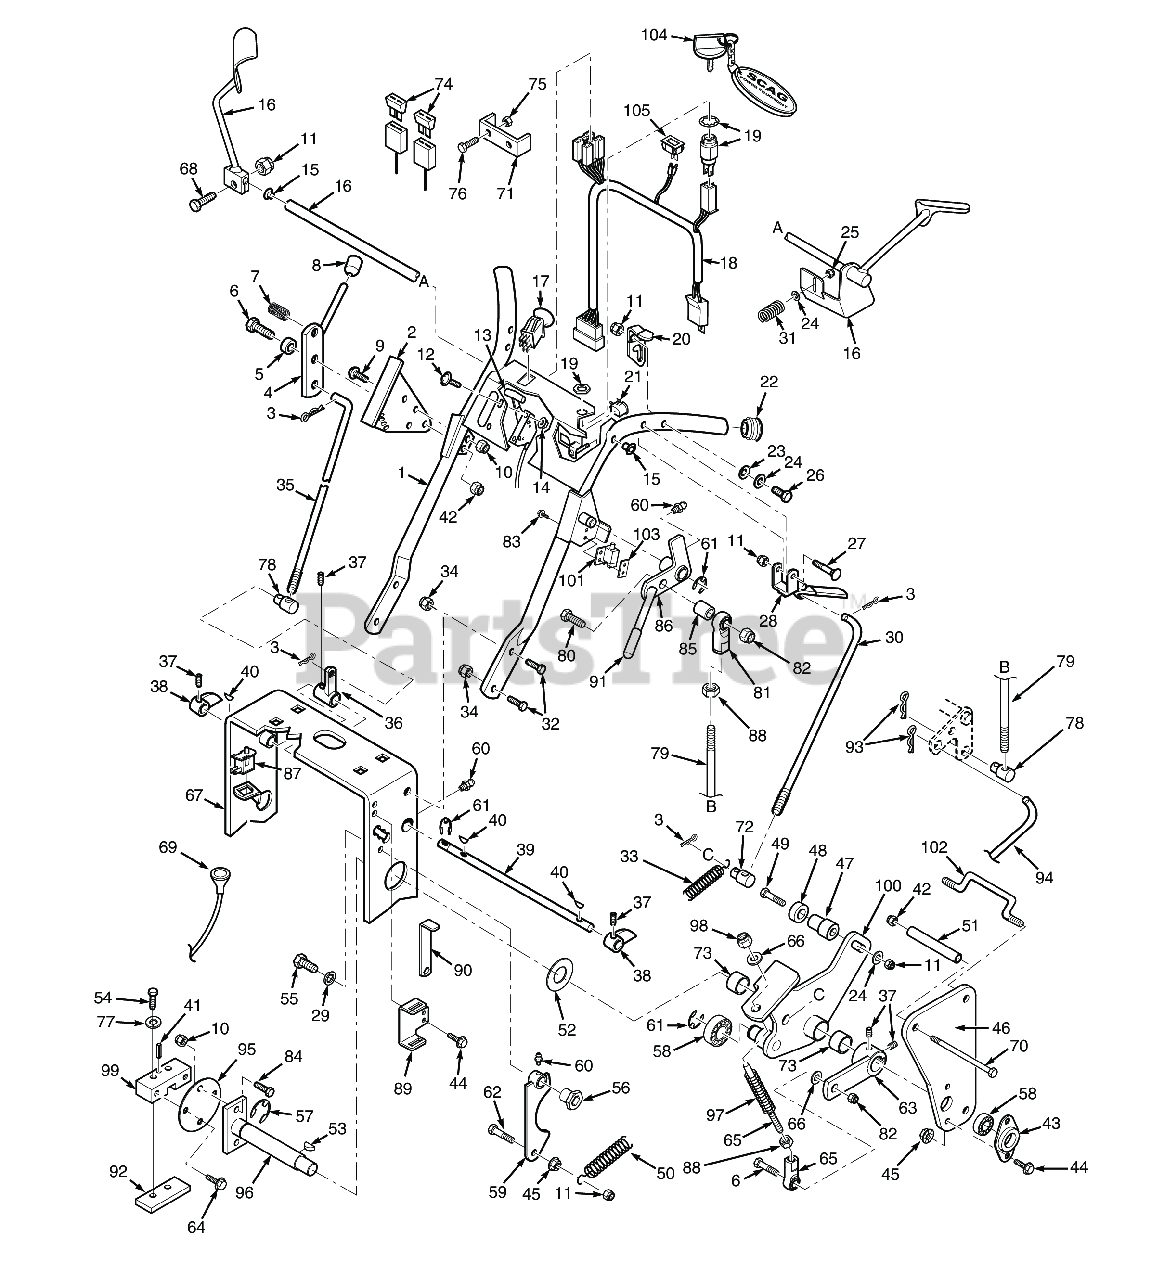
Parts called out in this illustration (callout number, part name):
1	Upper Handle Wlmt. W/Decals
2	QUADRANT, SPEED CONTROL
3	HAIR PIN, .08 DIAMETER X 1-3/16"
4	LEVER, SPEED ADJUSTMENT
5	BUSHING, SPEED ADJUSTMENT LEVER
6	Bolt, Hex Head, 3/8-16 x 1-1/2"
7	BALL PLUNGER
8	KNOB, SPEED ADJUSTMENT LEVER
9	CAPSCREW, 1/4-20 X .75 FLAT HD. HEX SOCKET
10	HEX, NUT, ELASTIC STOP LOCK, 1/4-20
11	HEX NUT, ELASTIC STOP LOCK, 5/16-18
12	SCREW, PHILLIPS WASHER HEAD #10-32 X 1/2"
13	Throttle Control (15KA & 17KA)
14	Nut, 5/16-18 Serrated Flange Hex Head
15	Bushing
16	Operator Presence Lever, RH
16	Handle, Oper. Presence-LH
17	Switch, PTO - 10 Amp
18	Wire Harness, Manual Start
18	Wire Harness, Electric Start
19	KEY SWITCH, MANUAL SRT.(INCL. HWD)
19	KEY SWITCH(INCLUDES MOUNTING HARDWARE)
20	Neutral Latch-RH 461241 Neutral Latch-LH
20	Neutral Latch Assembly, LH
21	SWITCH, NEUTRAL INTERLOCK
22	Plug, Handle Bar
23	Socket Head Capscrew #8-32 x 1/2"
24	Flatwasher, 5/16-.375 x .875 x .083 (35BV & 37BV-EFI)
25	HEX NUT, ELASTIC STOP LOCK, 5/16-18
26	Bolt, Hex Head 5/16-18 x 2-1/2" (x3) (35BV & 37BV-EFI)
27	Bolt, Hex Head 5/16-18 x 2-1/2" (35BV & 37BV-EFI)
28	Lever, Steering Control
29	Lockwasher, 3/8" Spring, Kawasaki FX / FS
30	Rod, Steering Control
31	Spring, Operator Presence
32	Capscrew, 3/8-16 x 1.0" Serrated Flange Hex Hd
33	Spring
34	NUT, 3/8-16 SERRATED FLANGE HEX HEAD
35	SPEED CONTROL ARM
36	Bellcrank, Speed Control
37	SETSCREW, 1/4-28 X 1/4 H. SOCK., KNURLED CUP
38	CAM, SPEED CONTROL(INCLUDES SETSCREW)
39	JACKSHAFT, SPEED CONTROL(FOR 20" DECK)
40	KEY, 1/8 X 1/2, WOODRUFF # 3
41	Roll Pin, Spring 3/16 x 3/4"
42	HEX NUT, ELASTIC STOP LOCK, 5/16-18
43	FLANGE, JACKSHAFT BEARING
44	Cpscrw, 5/16-18 x 1"Serrated Flange Hex Head
45	Nut, Serrated Flange 5/16-18 (Right Front Engine Mounting, Briggs and Kohler Only)
46	Plate, Side
47	Support, Neutral Support
48	BEARING, SPEED CONTROL BELLCRANK
49	BOLT, HEX HD., 5/16-18 X 1-3/4 FULL THREAD
50	SPRING, IDLER TENSION
51	Spacer, Side Plate
52	Flatwasher, 3/4 (.766 x 1.250 x .060)
53	KEY, WOODRUFF #9, 3/16 X 3/4"
54	SERR. FLG. HEX HEAD CAPSCREW, 5/16-18 X 3/4
55	Bolt, Hex Head, 3/8-16 x 1 Gr. 5
56	B ushing, Brake
57	RETAINING RING, 3/4" EXTERNAL "E"
58	BEARINGS, BALL, NEUTRAL RETURN
59	Cam, Neutral (incl. grease ftng.)
60	Greese Fitting, Straight 1/4 - 28
61	RETAINING RING, 5/8" EXTERNAL "E"
62	Bolt, Heax Head 5/16-18 x 1" (48V / 52V)
63	Lever, Speed Control
64	Bolt, Serrated Flange Hex Head 1/4 x 20 x 3/4"
65	Linkage Assembly
66	Flatwasher, 3/8" Special (.391 x .938 x .105)
67	Engine Deck (20" Wide) with Decals - Large Frame
68	Bolt, 5/16 - 18 x 1 - 1/4" Hex Head
69	Choke Control
70	Bolt, Hex Head 3/8-16 x 4-1/4"
71	BRACKET, FUSE HOLDER
72	Swivel Joint, Steering Rod
73	Bushing, oil lube - 3/4 ID x 1.0
74	FUSE, 20 AMP BLADE TYPE AUTOMOTIVE
75	HEX NUT, ELASTIC STOP LOCK # 10-32
76	Screw, #10-32 x 1.5" Phillips - 21KAE
77	Lockwasher, 1/4� Spring
78	SWIVEL JOINT, SPEED CONTROL ROD
79	Rod, Brake Lever
80	Capscrew, Hex Head 3/8-16 x 2.0"
81	Rod End, 3/8-24 RH Thread Female
82	HEX NUT, ELASTIC STOP LOCK, 3/8-16
83	Screw, Hex-Slotted Washer Head #10 32 x 3/4"
84	BOLT, HEX HEAD, 1/4-20 X 3/4 GR.5
85	Spacer, Idler
86	Parking Brake Lever w/Grip & Grease Fitting
87	SWITCH, NEUTRAL INTERLOCK
88	HEX NUT, 3/8-24 R.H. THREAD
89	Mounting Bracket, Wrench
90	Wrench
91	GRIP, PARKING BRAKE
92	CLAMP PLATE, PUMP CONTROL
93	COTTER PIN, HAIR - 0.94 X 1.62
94	Rod, Brake Lower
95	Plate, Coupler
96	Shaft, Pump Control
97	Spring, Tracking Adjustment
98	HEX NUT, ELASTIC STOP LOCK, 3/8-16
99	BLOCK, PUMP CONTROL
100	Control, LH (inc. bush. & decal)
100	Control, RH (inc. bush. & decal)
101	Switch, Interlock (see below)
102	Rod, Offset
103	Plate, Threaded
104	Key, Assembly w/Fob
104	Key w/Shroud Only
105	Hour Meter, Inductive
